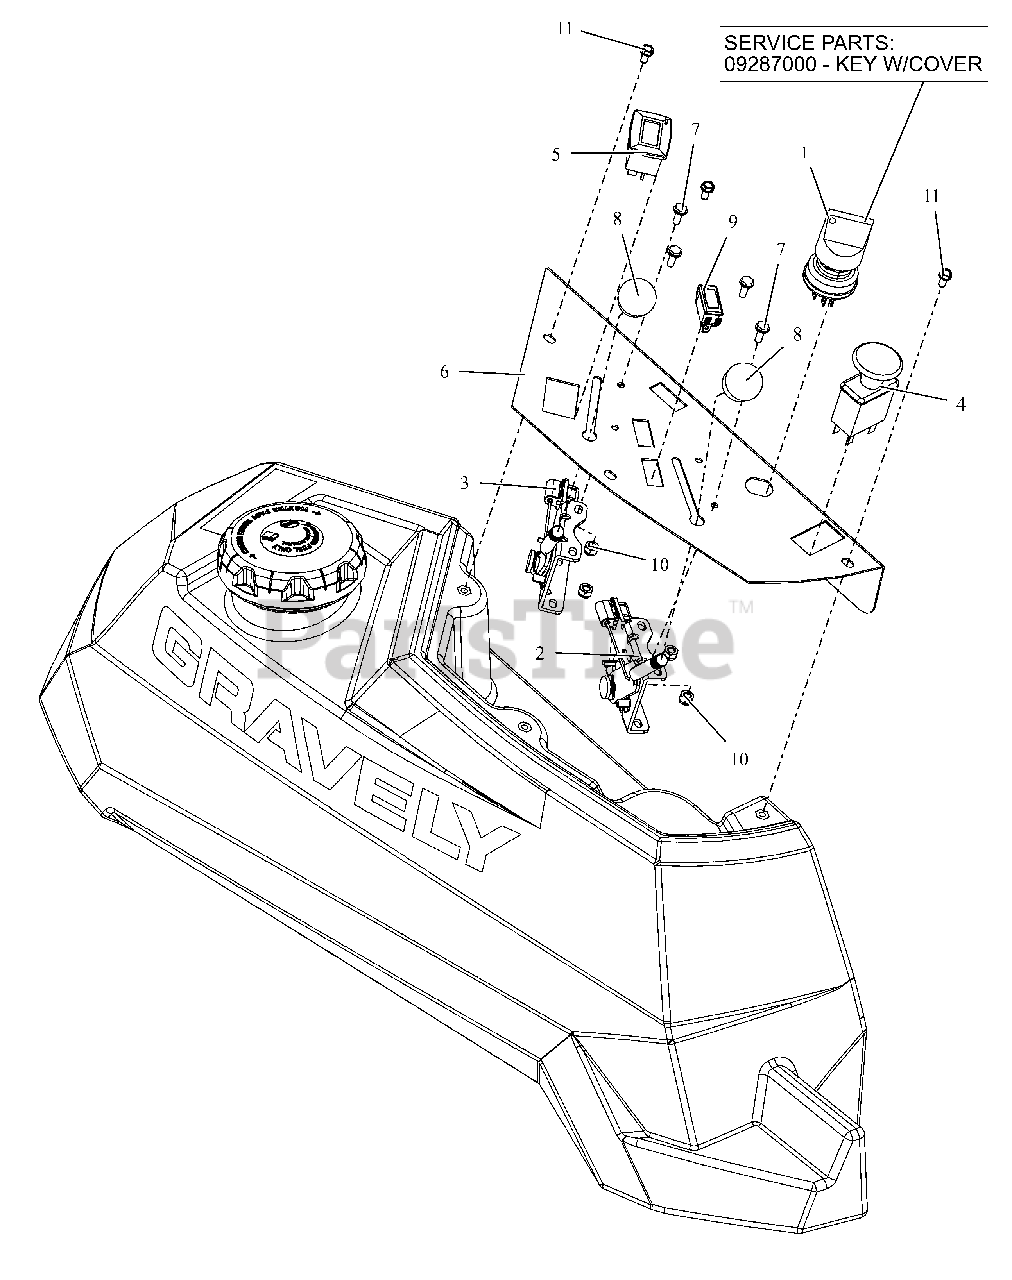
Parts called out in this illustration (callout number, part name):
1	SWITCH, IGNITION
1	KEY, W/ SHIELD
2	CABLE, PRO-CONTROL 28.50
3	CABLE, PRO-CONTROL 31.50"
4	SWITCH, CLUTCH
5	METER, HOUR W/MAINTENANCE
6	PT CONTROL PANEL - RED
7	@SCR-MCH 10-24X.50 HWH YWZC
8	KNOB-CONTROL-BLACK .38-16X.50
9	LIGHT,INDICATOR
10	@NUT-LK-NYL 10-24 W/INSRT YWZC
11	SCR-MCH 10-24X.38 HWHSTAINLESS
